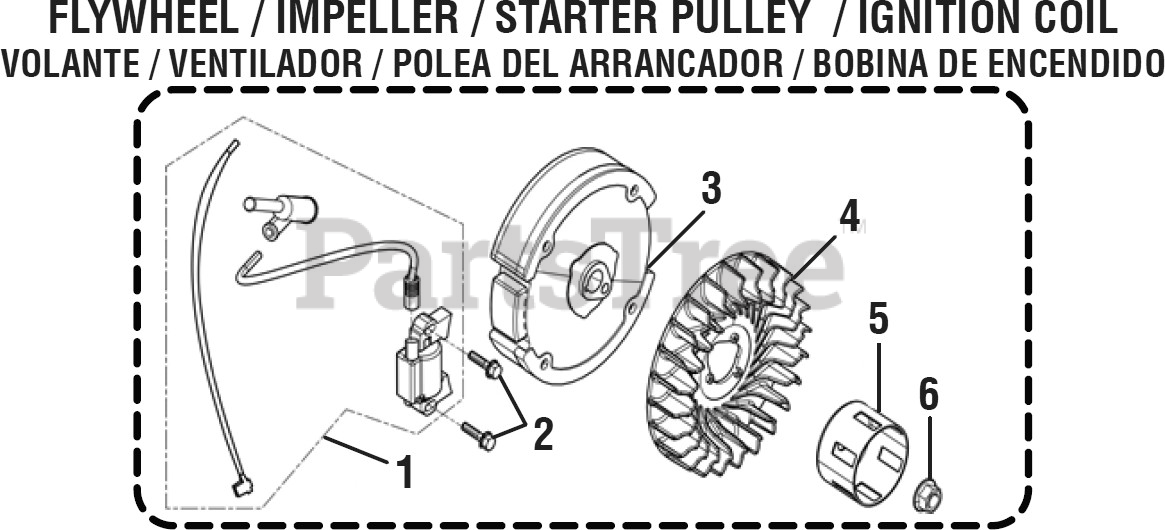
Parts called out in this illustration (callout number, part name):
1	Ignition Coil
3	Flywheel Assembly
4	Impeller
5	Starter Pulley
6	Flywheel Nut
